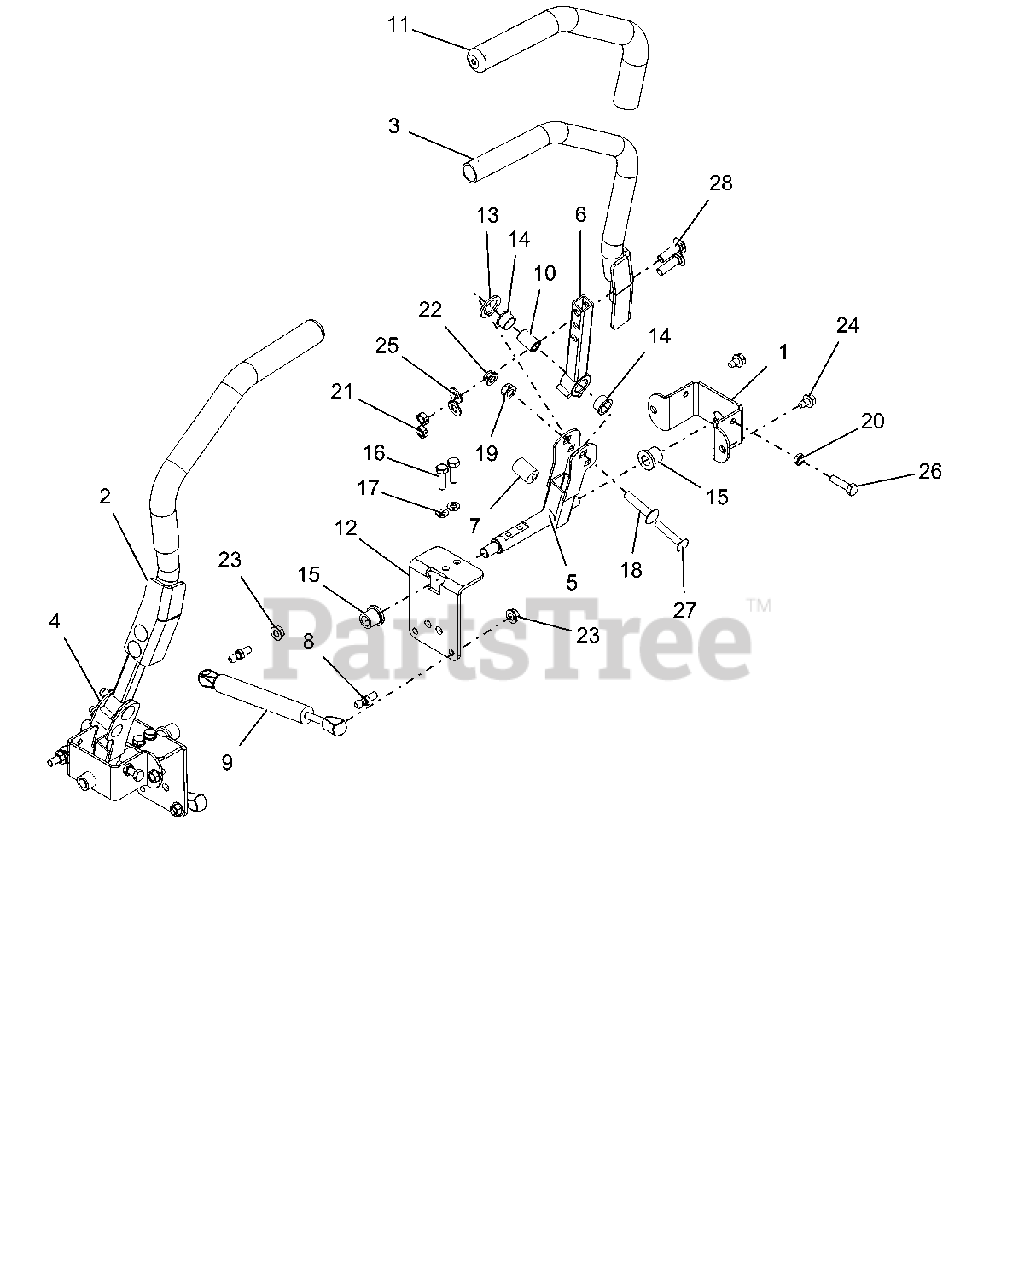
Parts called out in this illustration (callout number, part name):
1	BRKT, STEERING
2	WLDMT, STEERING HANDLE RH
3	WLDMT, STEERING HANDLE LH
4	WLDMT,STEERING ARM LOWER RIGHT
5	WLDMT,STEERING ARM LOWER LEFT
6	WLDMT, UPPER CONTROL ARM
7	BSHG,ECCEN .328X.750X1.01 PM
8	STUD- BALL
9	DAMPER, STABILUS
10	SPACER, .375X.625X.970 (PM)
11	GRIP, HANDLEBAR 15" FOAM
12	BRKT, STEEERING
13	WASHER, FRICTION .875X1.25X.10
14	BSHG-FLG, .625X.75X.450X.875
15	BSHG-FLG .515X.750X.745X1.00NY
16	BLT-HEX .31-18X1.00 GR8 YWZC
17	@WSHR-LK .31X.078 REG YWZC
18	BLT,RHSSN .38-16X1.75 G5 BFP
19	NUT-LK-CTR-FLG .38-16 YWZC
20	NUT- JAM .312-18 YWZC
21	@NUT-LK-CTR-JAM .375-16 YWZC
22	@NUT-LK-NYL-FLG .31-18 YWZC
23	@NUT-LK-TOP-FLG .31-18 YWZC
24	@SCR-TAP .31-18X.50 HWH TR YWZ
25	@WSHR-FL-STL.406X.812X.065 YWZ
26	@BLT-HEX .31-18X1.25 GR5 YWZC
27	BLT,RHSSN .31-18X1.75 G5 BFP
28	BLT,RHSSN .38-16X1.25 G5 BFP
